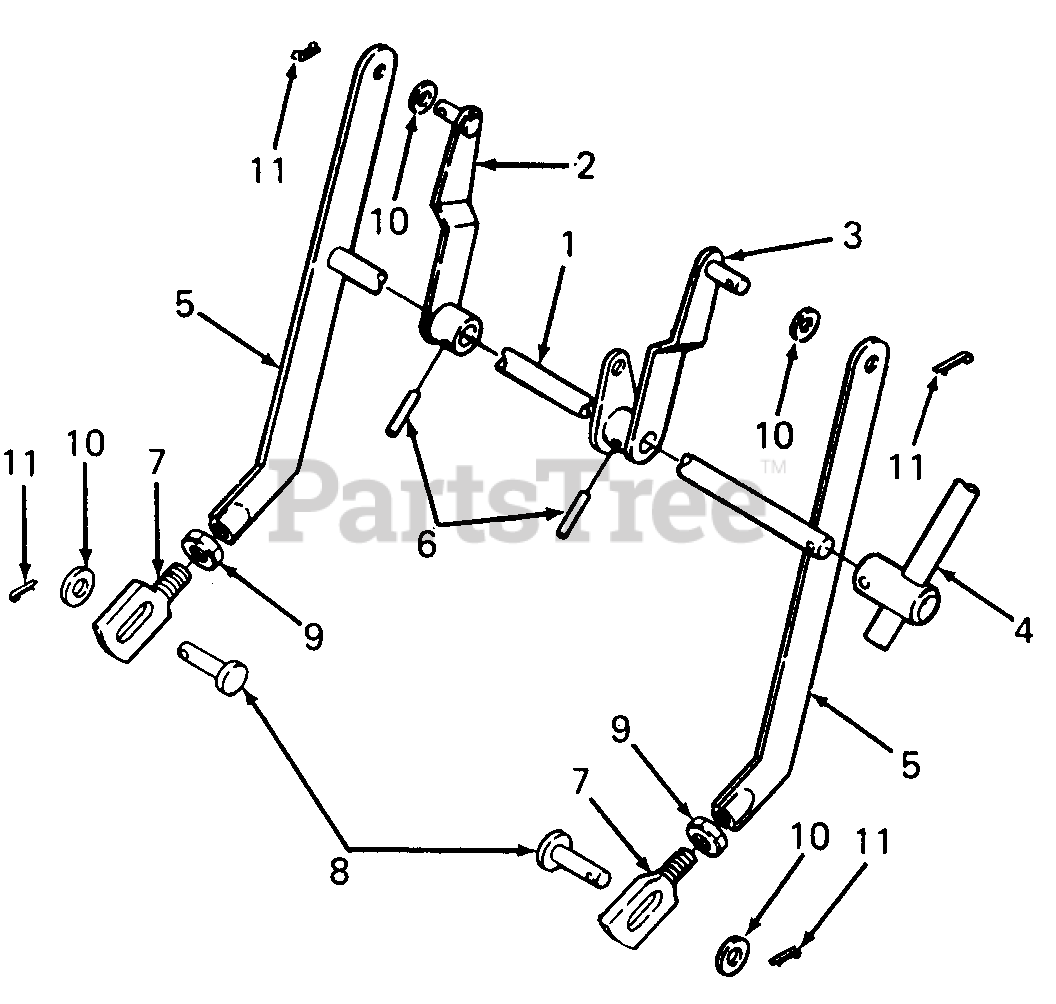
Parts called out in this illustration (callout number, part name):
1	Shaft, Lift
2	Arm Assy, Lift LH
3	Arm Assy, Lift RH
4	Lever, Lift
5	Bracket, Lift
6	Pin, 1/4 X 1.5 Long Slotted Roll
7	Bolt, Eye
8	Pin, Lift Bracket
9	Nut, 1/2-13
10	Washer, .510 X 1.0 X .06
11	Pin, Internal Cotter
